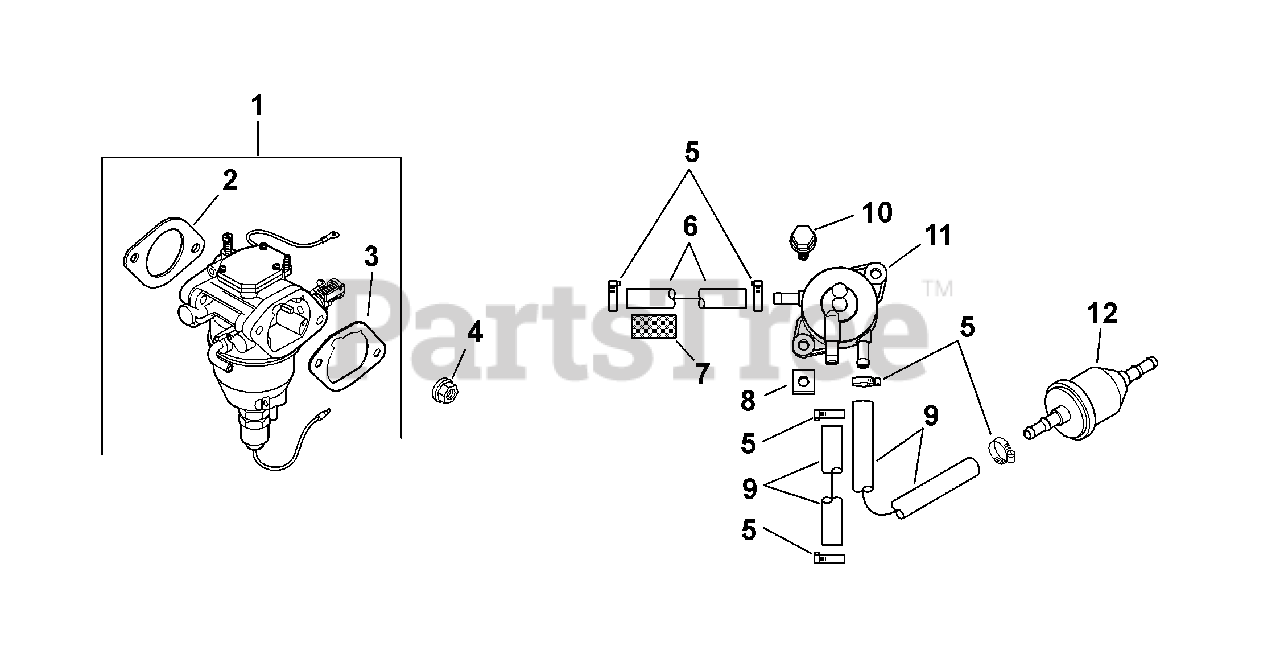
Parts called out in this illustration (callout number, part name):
1	Carburetor Kit w/ Gaskets (Inc. 2 & 3)
2	Carburetor Gasket
3	Air Cleaner Base Gasket
4	Flange Nut, M6 x 1.0
6	Flex Line, 11"
7	Insulating Sleeve, 14"
9	Fuel Line, 24"
10	Tap Screw, M6 x 1.7 x 18
